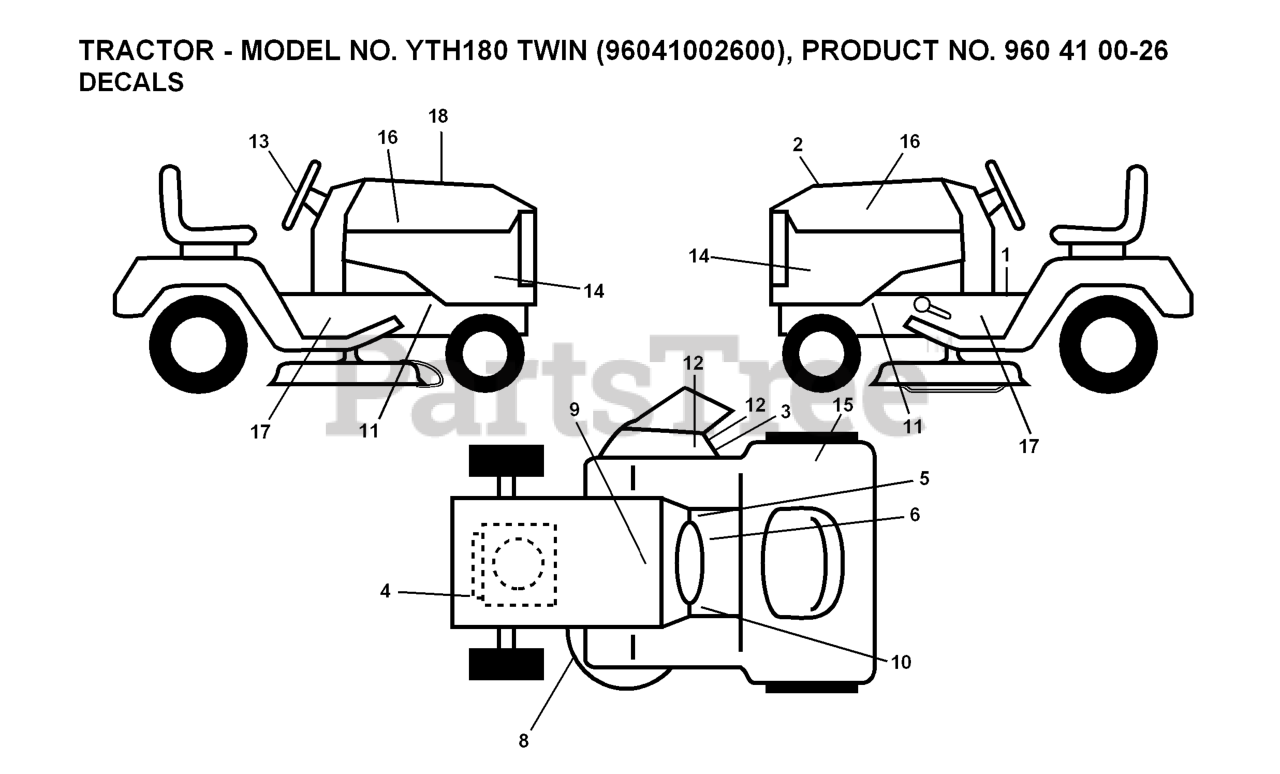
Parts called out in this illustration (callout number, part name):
1	LABEL
2	DECAL.HOOD.TOP.INSERT.
3	DECAL, DEFLECT WARNING
4	DECAL
5	DECAL PARK BRAKE
6	DECAL
8	DECAL V BELT SCHEMATIC
9	DECAL BTRY SYMBOLS
10	DECAL
12	DECAL.INTERNATIONL.CUTFINGER
13	DECAL.WHEEL.STRG.LGN.H
15	Decal, Fender 100 DB/CE
16	DECAL.HOOD.NAMELOGO.HUSQ
